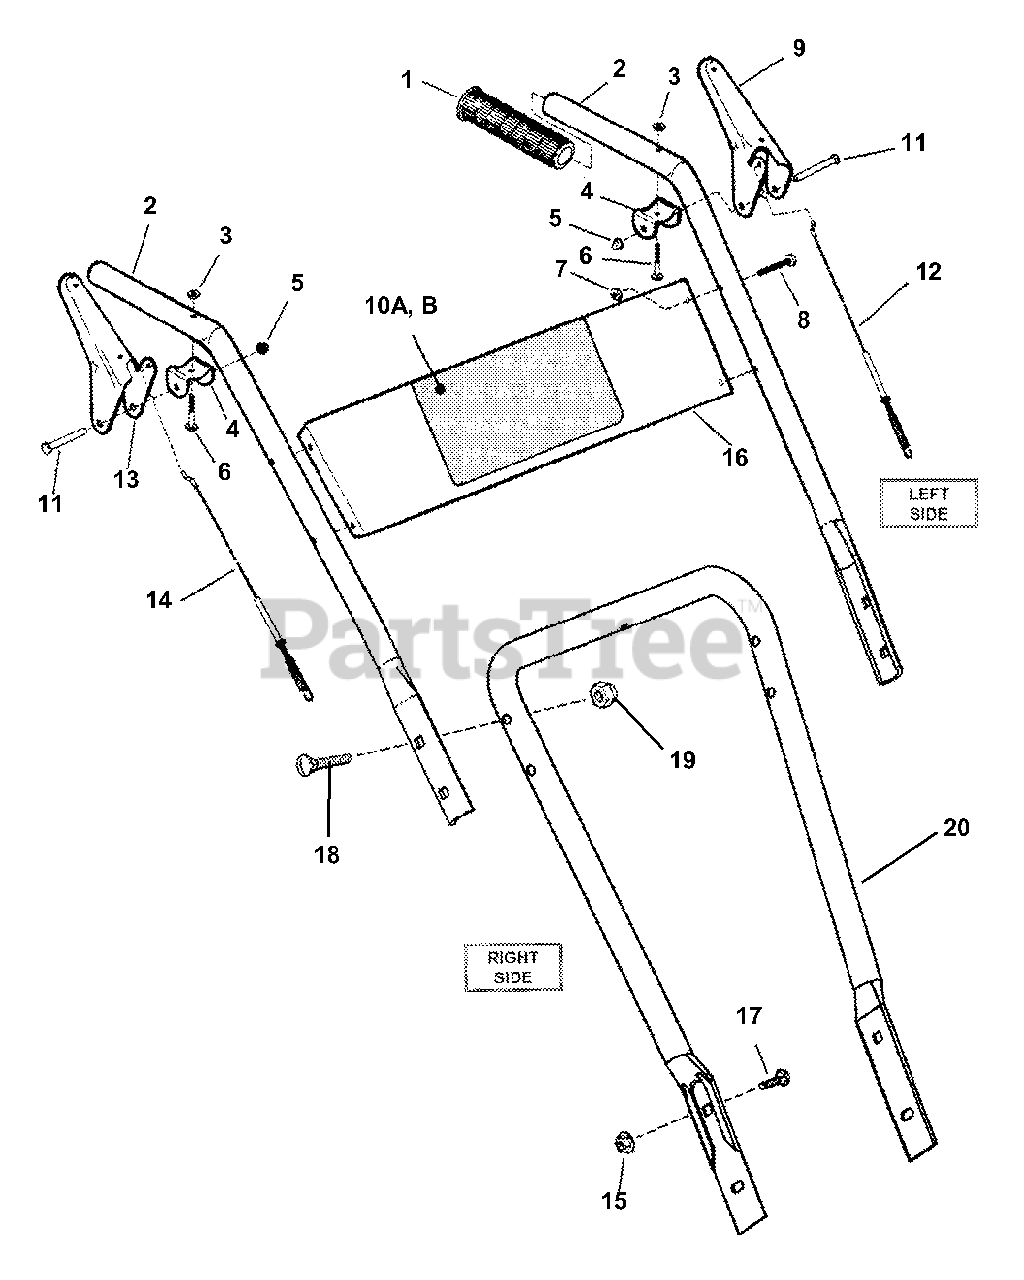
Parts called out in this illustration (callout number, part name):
1	GRIP, Handle
2	BAR, Handle (Right Hand)
3	NUT, 1/4-28 Hex Top Lock
4	BRACKET, Handle
5	NUT, 1/4" Push
6	SCREW, 1/4-28 x 1-3/8" Hex Head Cap, Grade 5
7	NUT, 5/16-18 Hex Top Lock, Grade B
8	SCREW, 5/16-18 x 1-1/2" Hex Head Cap, Grade 5
9	HANDLE, Left Side
10A	DECAL, Snapper (I55224 Model)
10B	DECAL, Snapper (EI55224 Model)
11	PIN, 1/4x 1-7/8" Clevis
12	CABLE, Clutch Left Side (Short)
13	HANDLE, Right Side
14	CABLE, Auger Right Side (Long)
15	NUT, 5/16-18 Hex Flange Lock, Grade 5
16	PANEL, Control
17	BOLT, 5/16-18 x 5/8" Short Neck Carriage, Grade 5
18	BOLT, 5/16-18 x 2" Square Neck Carriage, Grade 5
19	NUT, 5/16-18 Hex Nyloc
20	BAR, Handle (Lower)
